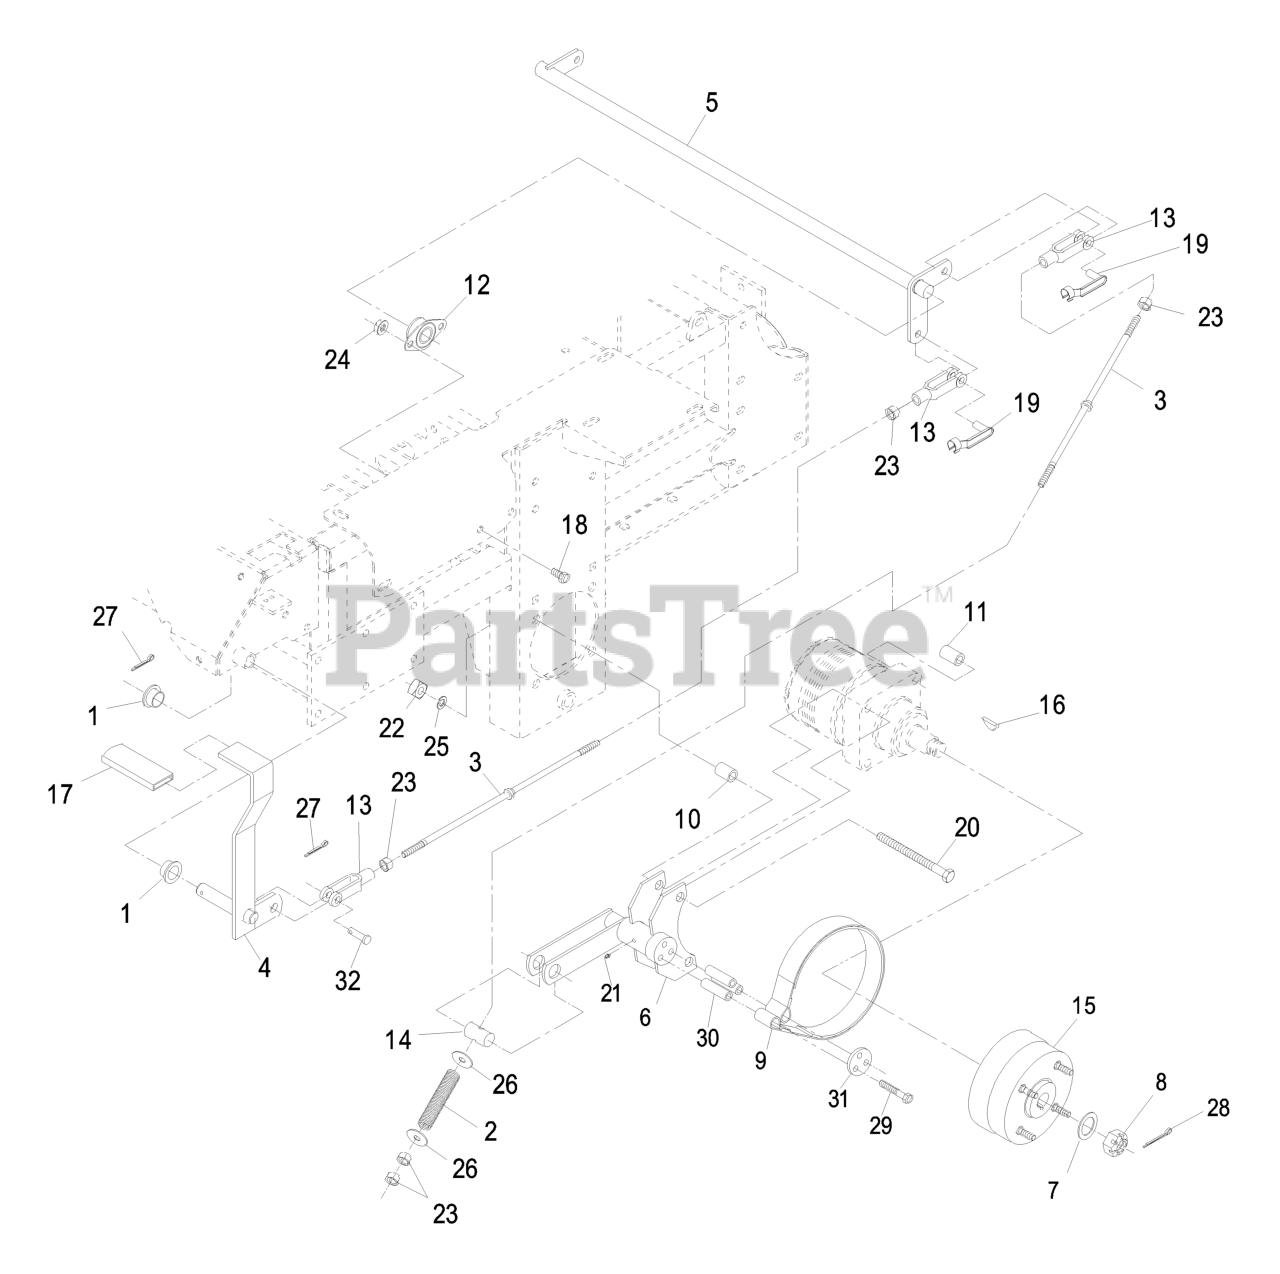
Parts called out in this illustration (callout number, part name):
1	BEARING-CONTROL
2	SPRING-BRAKE
3	ROD-BRAKE
4	BRAKE LEVER ASM
5	SHAFT-BRAKE
6	BRACKET-BRAKE
7	WASHER-SPACER
9	BAND,BRAKE
10	SPACER-WHEEL, SHORT
11	SPACER-WHEEL, LONG
12	BEARING-FLANGE, SIDE
13	YOKE-LINKAGE, BRAKE
14	PIN-TRUNION
15	WHEEL HUB ASM
16	KEY-WOODRUFF
17	GRIP-LEVER
18	SCREW-HH
19	PIN-SPRING, CLEVIS
20	SCREW-HH
21	FITTING-GREASE
23	NUT-HEX
24	NUT-HHF, WHIZ
25	WASHER-LOCK
26	WASHER-FLAT
27	PIN-COTTER
28	PIN-COTTER
29	SCREW-HH
31	RETAINER-BAND, BRAKE
32	PIN-CLEVIS
